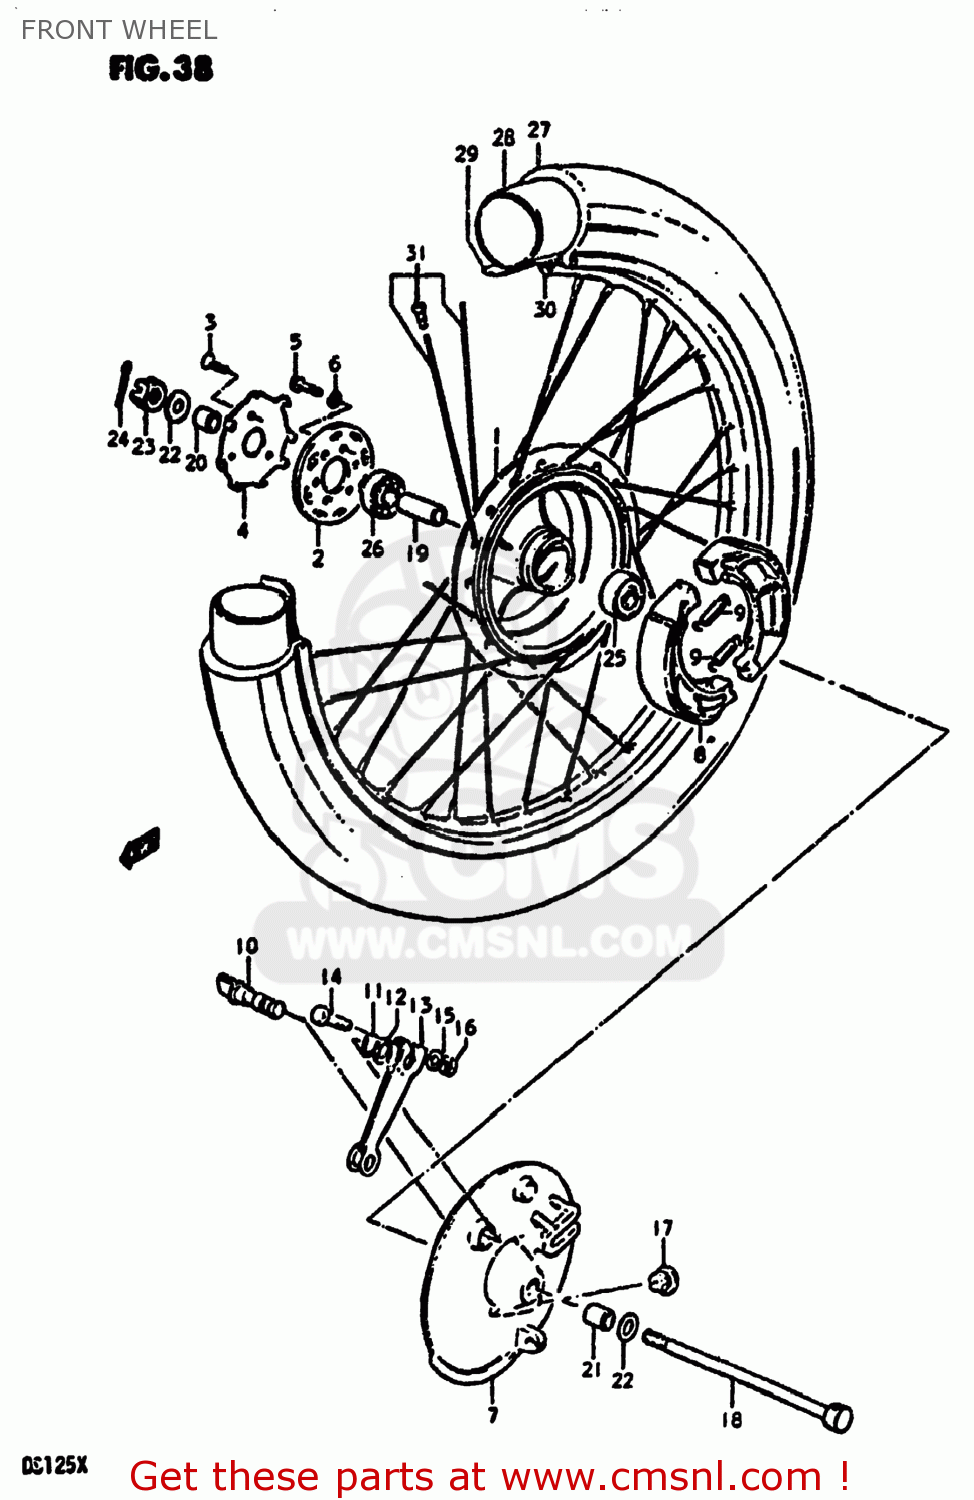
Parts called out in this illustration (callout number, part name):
1	HUB,FR WHEEL
2	FLANGE,FR HUB,R
3	SCREW
4	RETAINER,FR HUB BEARING,R
5	BOLT, UPPER
6	LOCK WASHER
7	PANEL,FRONT HUB
8	SHOE,BRAKE
9	SPRING(L:34)
10	CAM,FRONT BRAKE
11	O-RING (D:2.4 ID:13.8)
12	WASHER (14.5X22X1.6)
13	LEVER,FR BRAKE CAM
14	BOLT(6X33)
15	WASHER
16	NUT
17	CAP(OD:17)
18	AXLE,REAR
19	SPACER (12.6X19X52)
20	SPACER (12.2X19X18.5)
21	SPACER(12X20X34.5)
22	WASHER
23	NUT 12MM
24	COTTER PIN
25	BEARING
26	BEARING, RH
27	TIRE,FRONT
28	TUBE
29	PROTECTOR,WHEEL,INNER
30	RIM,FR WHEEL(1.60X21)
31	SPOKE SET,FR
